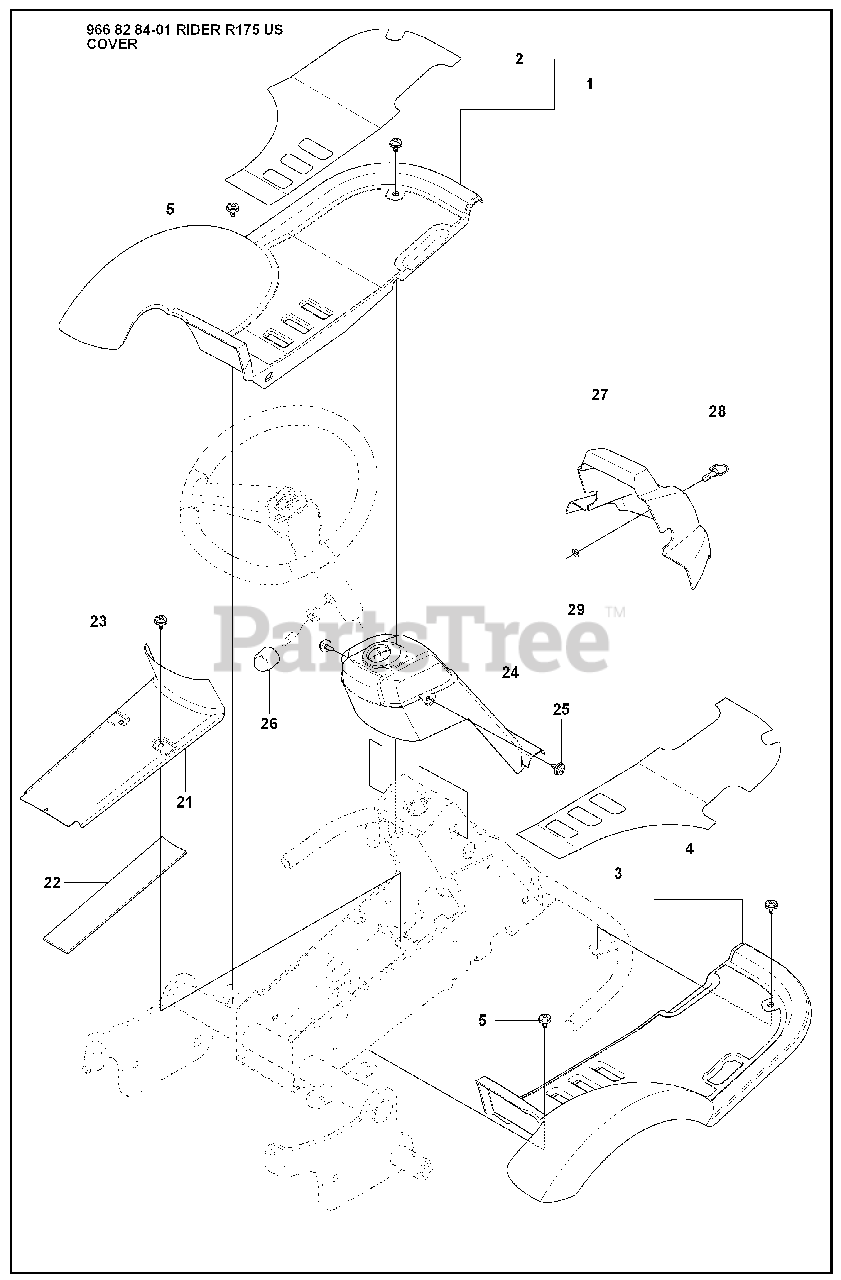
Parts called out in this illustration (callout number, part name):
1	FOOT PLATE
3	FOOT PLATE
26	PROTECTIVE COVER
28	BOLT
